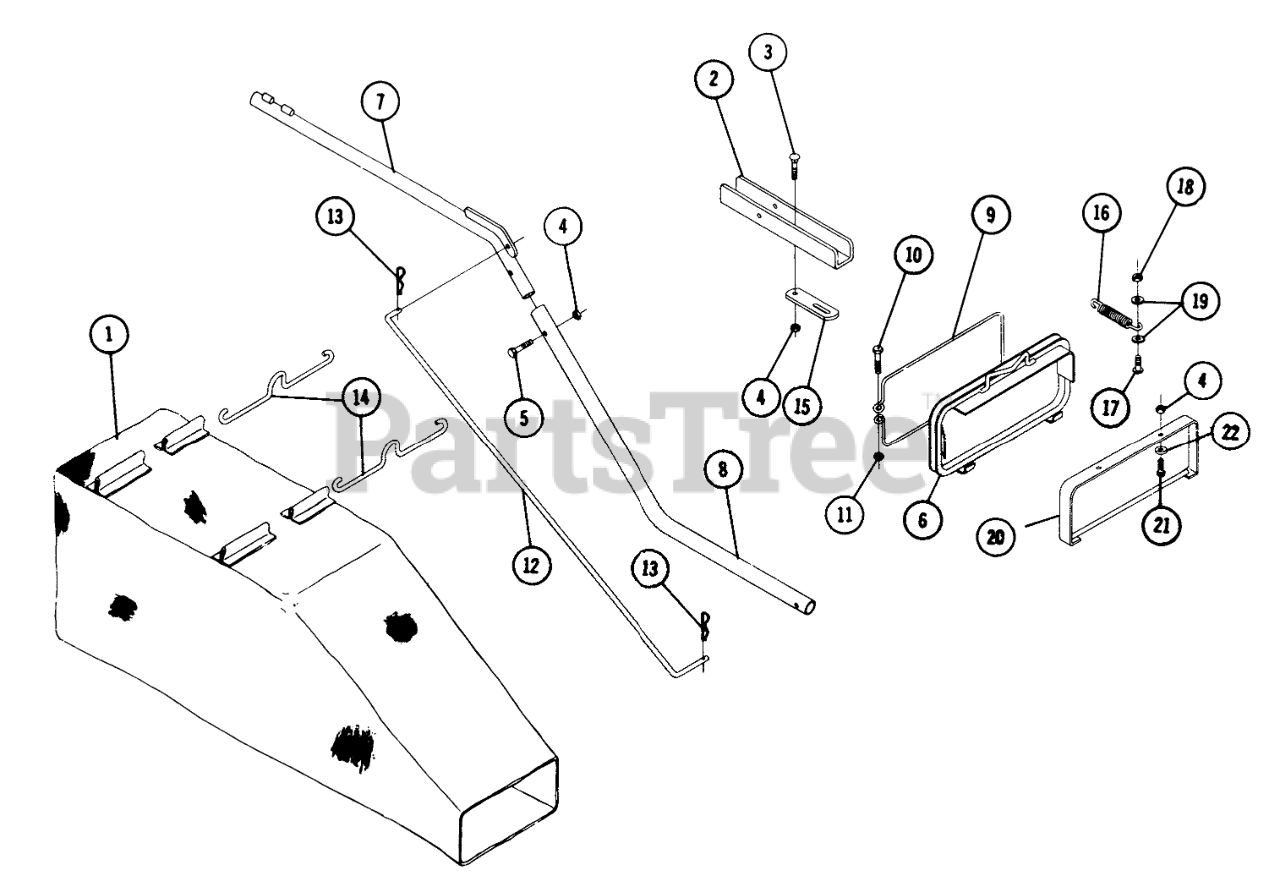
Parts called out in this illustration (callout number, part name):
2	Channel
3	Bolt-Carriage
4	Nut
5	Bolt
6	Frame
7	Upper Arm
8	Arm-lower
10	Bolt
11	Nut
12	Link
13	Hairpin Cotter
14	Hook
15	Link
16	SPRING R
17	PAN HEAD SCREW-4
18	NUT
19	Washer
20	Strap Assembly
21	Screw
22	Spacer
